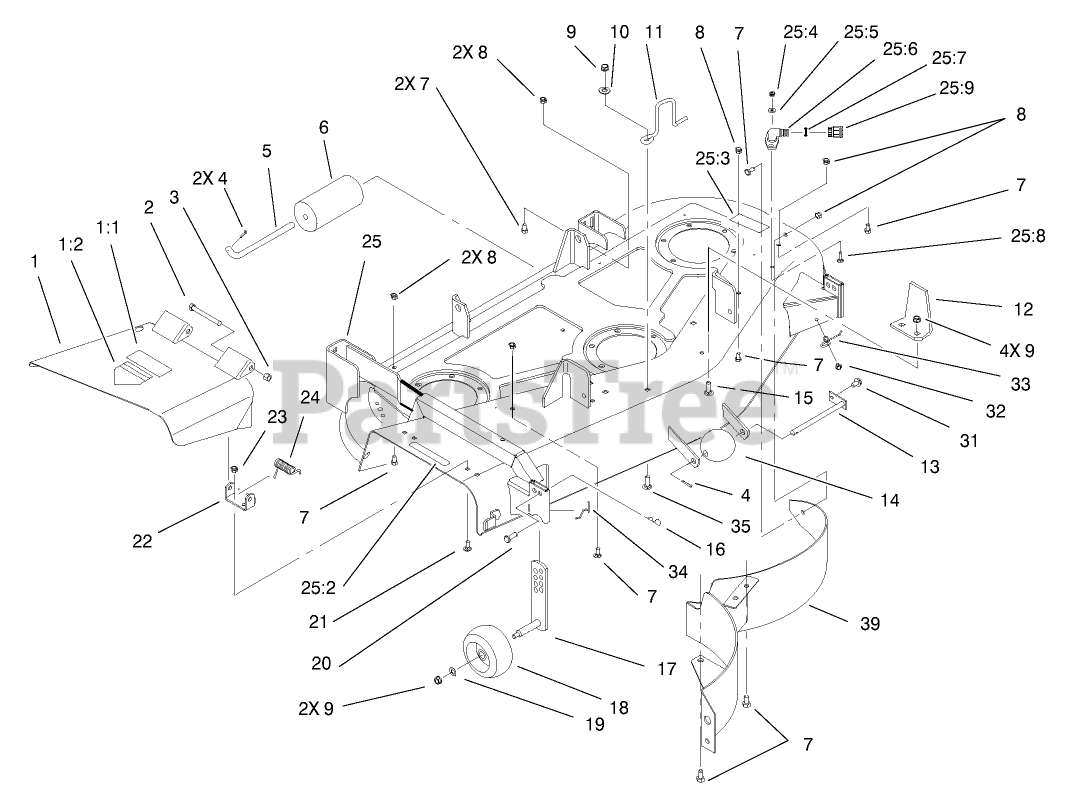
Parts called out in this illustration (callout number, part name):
1:1	DECAL-DANGER
1:2	DECAL-DANGER
2	SCREW-HH
3	NUT-HEX
4	PIN-COTTER
5	SHAFT-ROLLER, REAR
6	ROLLER-DECK
7	SCREW-HH
8	NUT-LOCK, NI
9	NUT-LOCK, NI
10	WASHER
13	SHAFT ASM
14	ROLLER
15	BOLT-CARR
16	PIN-HAIR
17	GAGE-WHEEL
19	WASHER-FLAT
20	PIN-CLEVIS
21	SCREW-CARR
22	BRACKET-PIVOT
23	NUT-LOCK, NI
24	SPRING
25:2	DECAL-CAUTION
25:2	DECAL-DANGER
25:3	DECAL-DANGER
25:4	NUT-LOCK, NI
25:5	WASHER-FLAT
25:7	O-RING
25:8	BOLT-CARR
25:9	CONNECTOR-HOSE
31	SCREW-HWHTF
32	SCREW-HHFTF
34	SPRING-GAGE WHEEL, RH
35	SCREW-CARR
39	BAFFLE ASM-MULCH, LH
